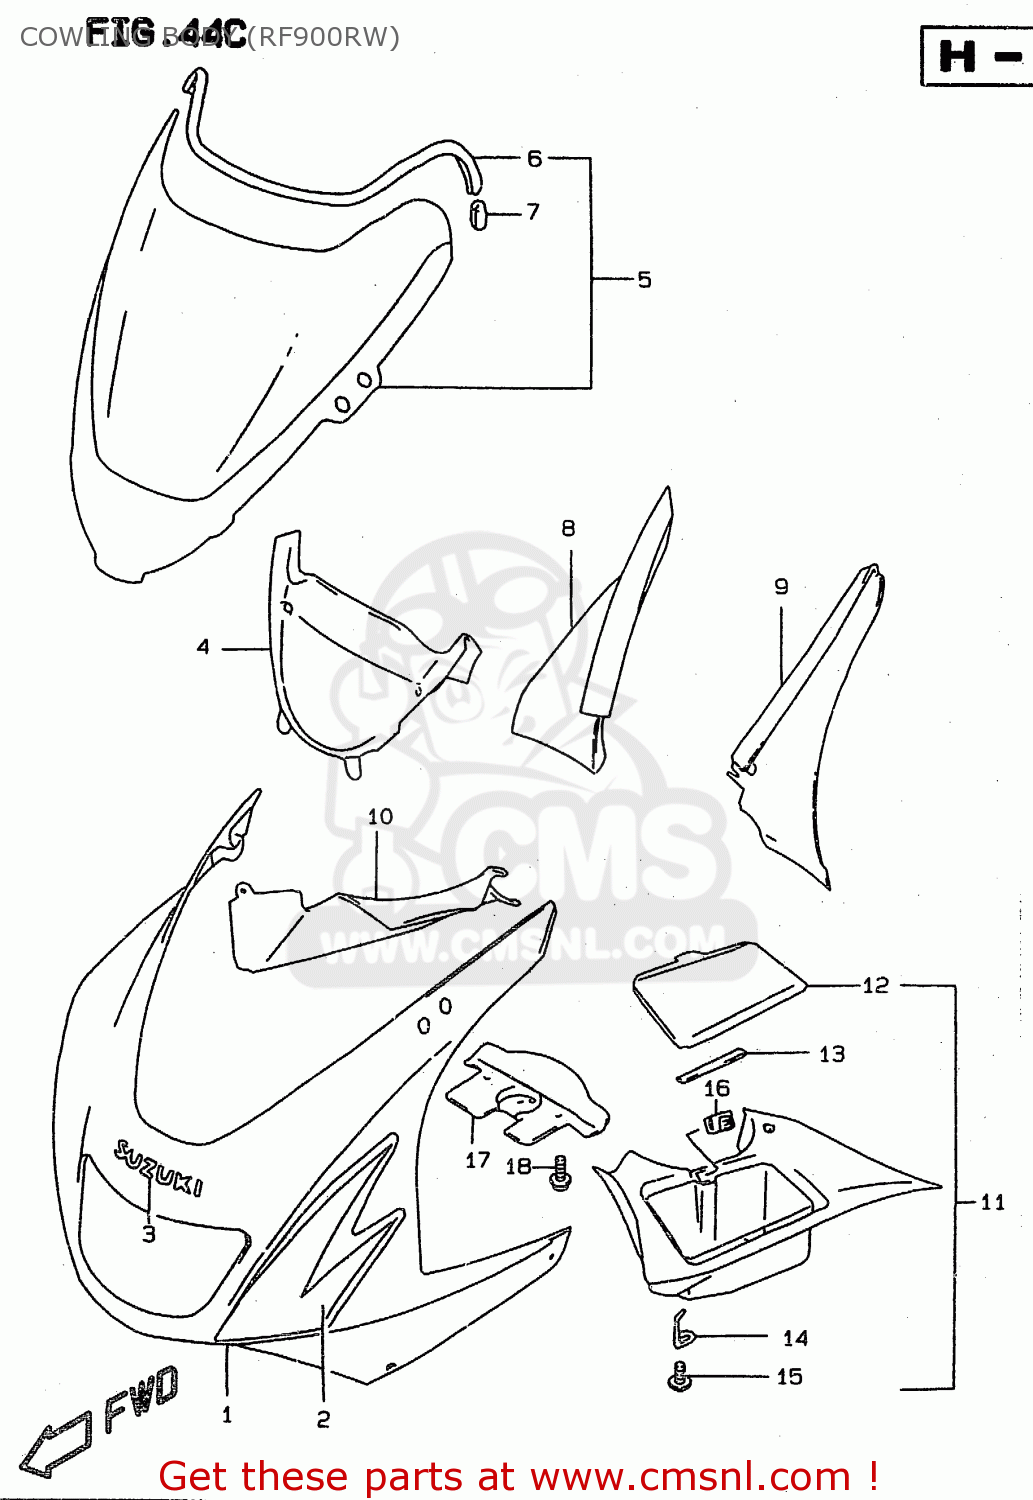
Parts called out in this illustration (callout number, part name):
1	COWLING ASSY,BODY
2	TAPE SET,COWL BODY FR
3	EMBLEM,COWLING UPR
4	PANEL,COWLING CTR
5	WINDSCREEN SET
6	MOLDING WINDSCREEN
7	CLIP,WINDSCREEN MOLDING
8	PANEL,UPR,R
9	PANEL,UPR,L
10	PANEL,SIDE,R
11	PANEL ASSY,SIDE,L
12	LID,PANEL BOX
13	CUSHION,LID
14	HINGE,PANEL LID
15	SCREW
16	LOCK,I/P CTR BOX
17	COVER,COWLING FR LWR
18	BOLT(6X12)
